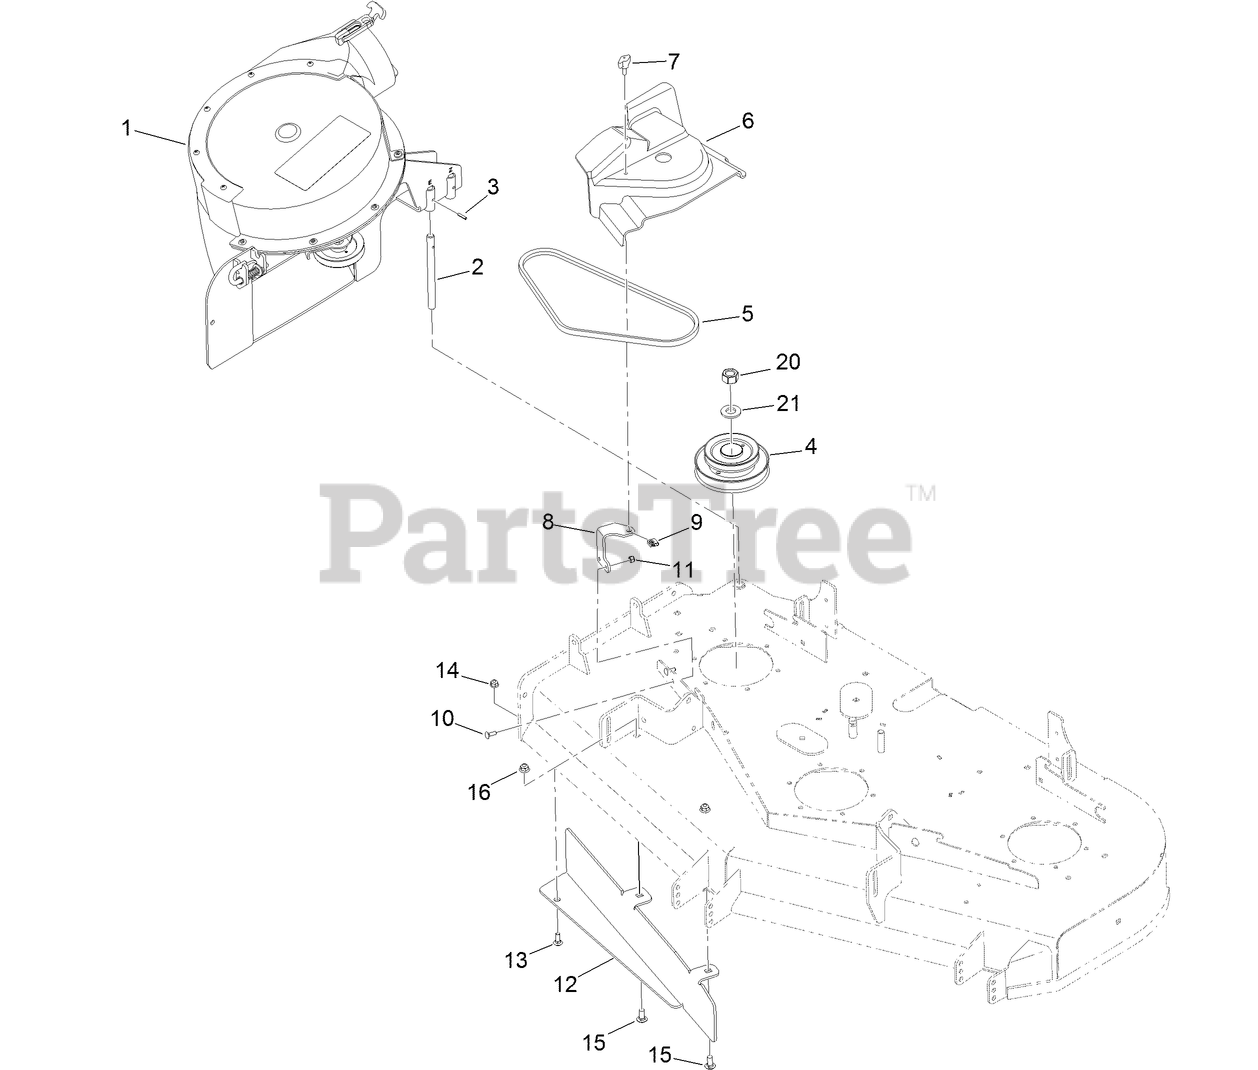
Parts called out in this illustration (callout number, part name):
1	BLOWER ASM
2	SHAFT-CATCHER, GRASS
3	PIN-ROLL
4	DRIVE-JACKSHAFT
5	BELT-DRIVE, BLOWER
6	COVER-BELT
8	BRACKET-COVER, BELT
9	NUT-SPEED
10	BOLT-CARR
11	NUT-LOCK, NI
12	BAFFLE-BAGGER
13	SCREW-CARR
14	NUT-HF, NI
15	SCREW-CARR
16	NUT-HF, NI
20	NUT-HEX
21	WASHER
